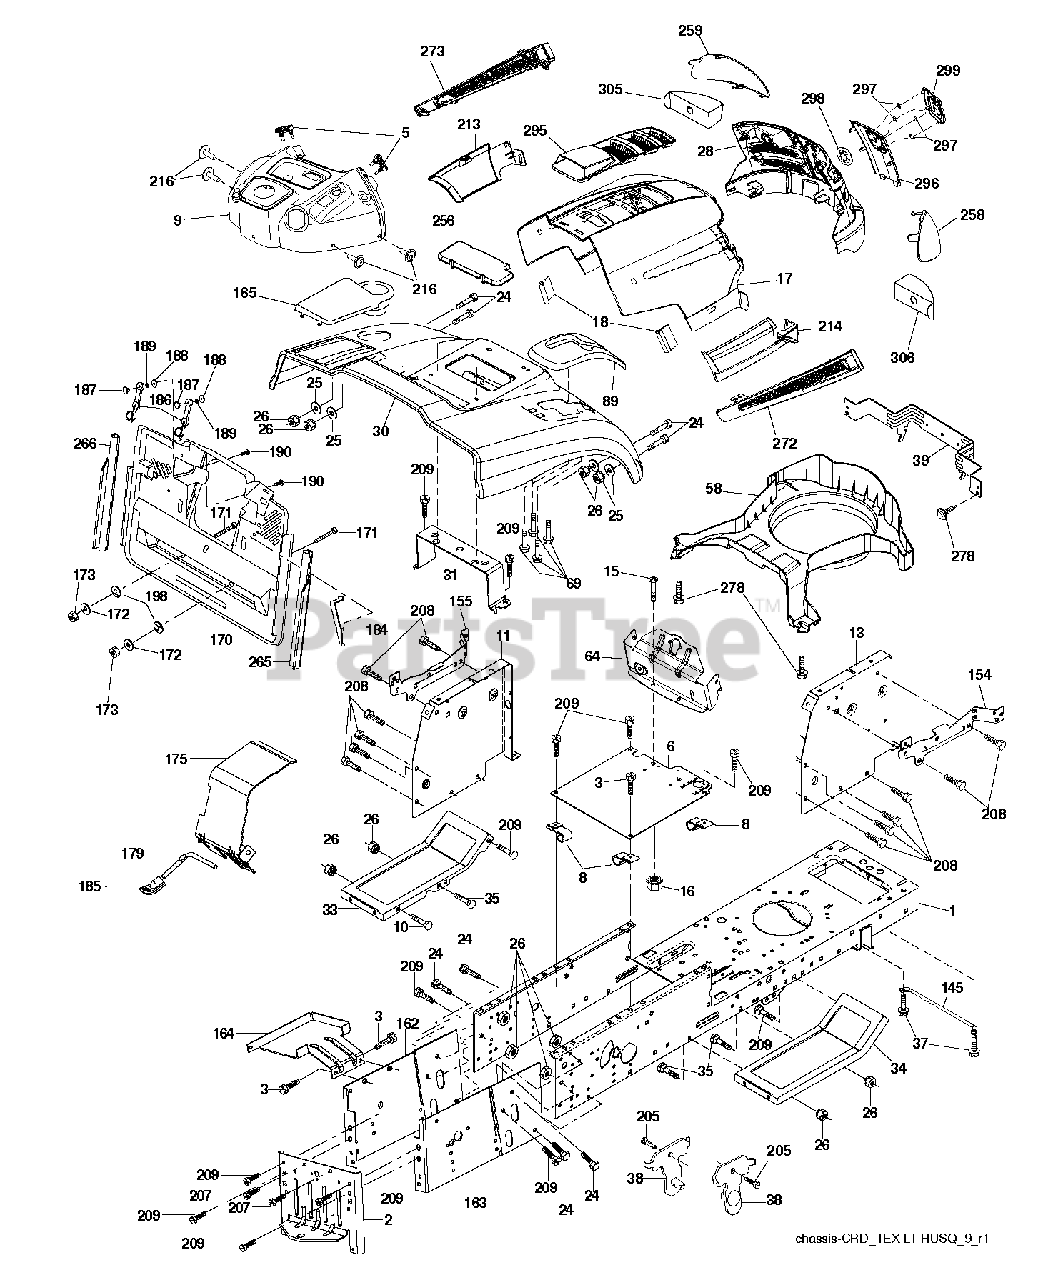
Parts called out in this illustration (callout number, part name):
2	DRAWBAR
3	SCREW 3/8-16X3/4
5	BUMPER DASH
6	PLATE
8	CLIP,INSULATOR
10	BOLT D
11	PANEL.DASH.LH.LTX
13	PANEL ASM, DASH RH
16	NUT
17	HOOD.HUSQVARNA.LT.ORANGE
18	BUMPER.HOOD.TEX.HUSQVARNA
25	WASHER
26	NUT
28	GRILLE.SVC.HUSQVARNA.GREY
30	FENDER.PNT.CRD.MS-668
31	BRACKET SUPPORT FENDER
33	FOOTREST.PNT.LH.GREY
34	FOOTREST.PNT.RH.GREY
37	SCREW LT
38	BRACKET ASM PIVOT MOWER REAR
39	BRACKET PIVOT
69	SCREW.HI-LO.CONSOLE
89	CONSOLE.CRD.AUTO.GRY
145	ROD.PIVOT.HOOD
162	BRACKET
163	BRACKET EXTEN CHASSIS RH CRD
165	COVER.BATT.CUPHOLDER.CRD
172	WASHER
175	DOOR TRAP
179	ROD PIVOT FBI
184	BRACKET.ACTUATOR.BAGGER.SRD
185	KNOB.BRAKE.PARKING.ROD
186	LATCH ASSY
187	WELDNUT
189	LOCKWASHER (3 2)
190	SCREW
207	SCREW, 5/16-18 X 1/2
208	SCREW 3/8-16X1/2
209	SCREW, 3/8-16X3/4
213	SKIRT.SIDE.HUSQVARNA.LT.LEFT
214	SKIRT.SIDE.HUSQVARNA.LT.RT
216	SCREW HEXWSHR 1/4-20X3/4
256	FENDER.PNT.CRD
258	LENS.HUSQVARNA LT.RH
259	LENS.HUSQVARNA LT.RH
265	SEALING
266	SEALING
272	VENT.SIDE.HUSQVARNA.LT.RT
273	VENT.SIDE.HUSQVARNA.LT.LFT
278	SCREW.#10 X 0.750.BOS
296	TRIM.HUSQ LT.668
297	CLIP.RETAINER.TINNER.
298	NUT PUSH M
299	RP LOGO
305	INSERT REFLECTIVE
306	INSERT.REFLECTIVE.RH.
